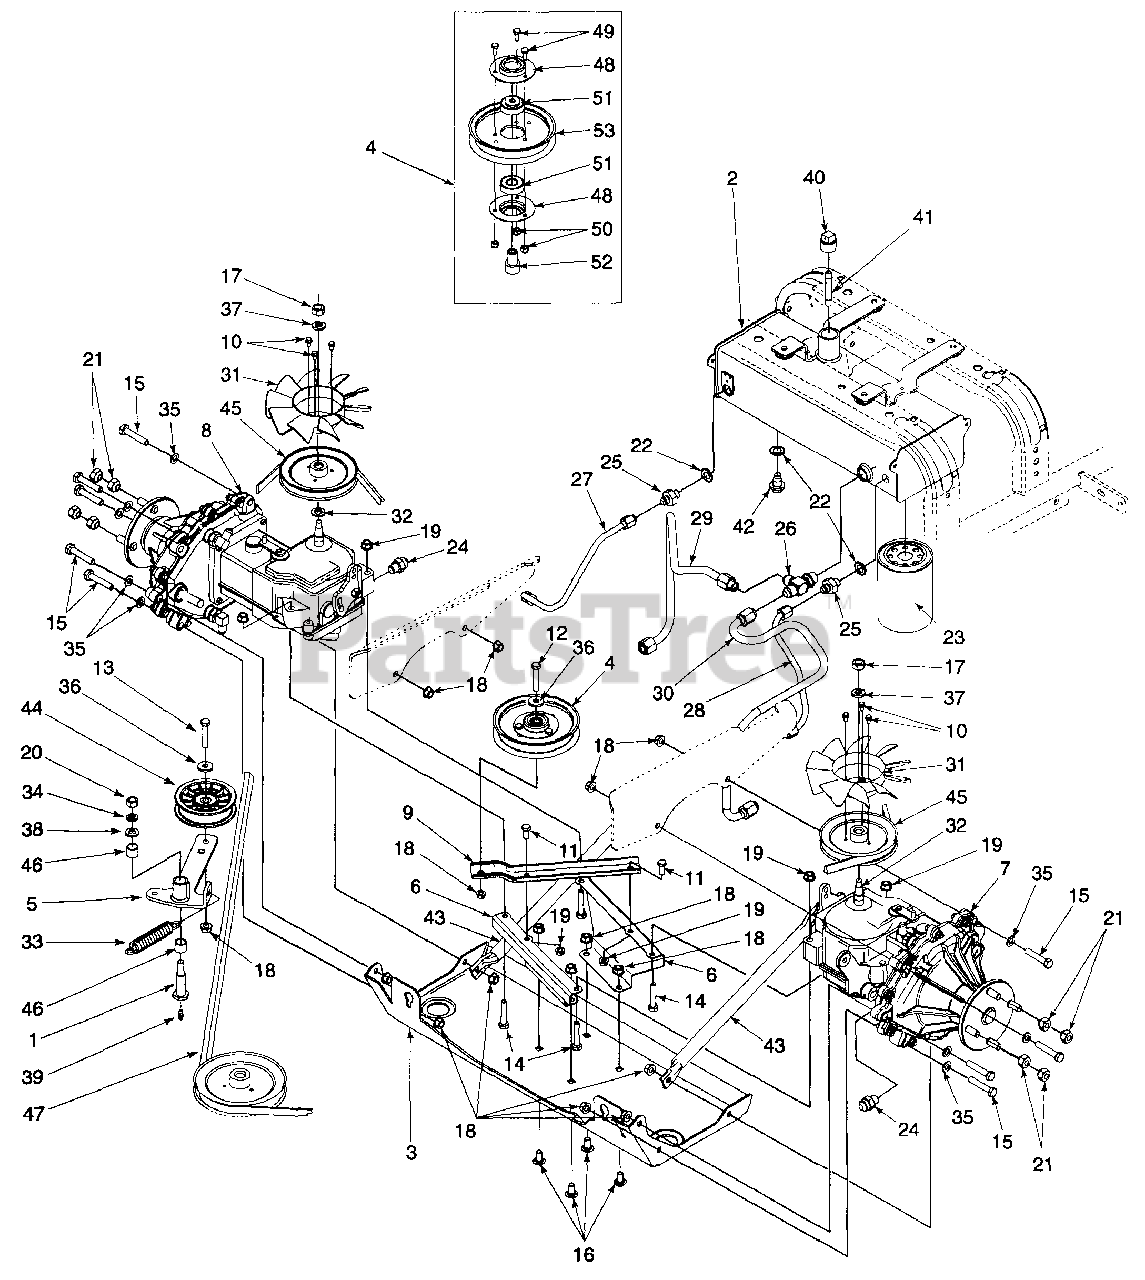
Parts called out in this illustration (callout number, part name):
1	Shoulder Bolt, Special
3	Plate Ass'y, Skid
4	Pulley Ass'y, Idler 5.0 in
8	Transmission Ass'y LH
11	Screw, Hex Cap 5/16-18 x .75 GR5
12	Screw, Hex Cap 3/8-16 x 2-1/4 GR5
13	Screw, Hex Cap 3/8-16 x 1-3/4 GR5
14	Screw, Hex Cap 5/16-18 x 2.0 GR5
15	Screw, Hex Cap 3/8-16 x 2.0 GR5
16	Bolt, Carriage, 3/8-16 x .75
17	Nut, Hex, 1/2-20
18	Nut, Hex Flange Lock, 3/8-16
19	Nut, Hex Flange Lock, 5/16-18 GR5
20	Nut, Hex, 7/16-14
21	Nut, Lug, 7/16-14
22	Seal, Drain Plug
23	Filter Element, Oil
24	Fitting, Connector, 1/2 x 3/8
25	Fitting, Connector
26	Fitting, Tee, 1/2 x 1/2 x 3/4
27	Tube, Inlet LH
28	Tube, Inlet RH
29	Tube, Outlet LH
30	Tube, Outlet RH
31	Fan, 10 Blade
32	Wire Ring
33	Spring, Extension
34	Washer, Lock, 7/16
35	Washer, Flat, .406 x .75 x .06
36	Washer, Flat, .385 x 1.0 x .135
37	Washer, Lock, 1/2
38	Washer, Flat, .469 x .875 x .105
39	Fitting, Grease
40	Plug, Pipe, w/Vent 3/4 NPTF
41	Tube, Dipstick
42	Plug, Oil Drain
45	Pulley, Transmission
46	Bearing, Sleeve, .628 x .75 x .625
47	V-Belt, Transmission Drive A-Section x 54.24 Lg
48	Cup, Bearing
49	Screw, Hex Cap, 1/4-20 x .62 GR5
50	Nut, Hex Insert Lock, 1/4-20
51	Bearing, Ball
52	Spacer, Idler
53	Pulley, Idler 5.0 in
